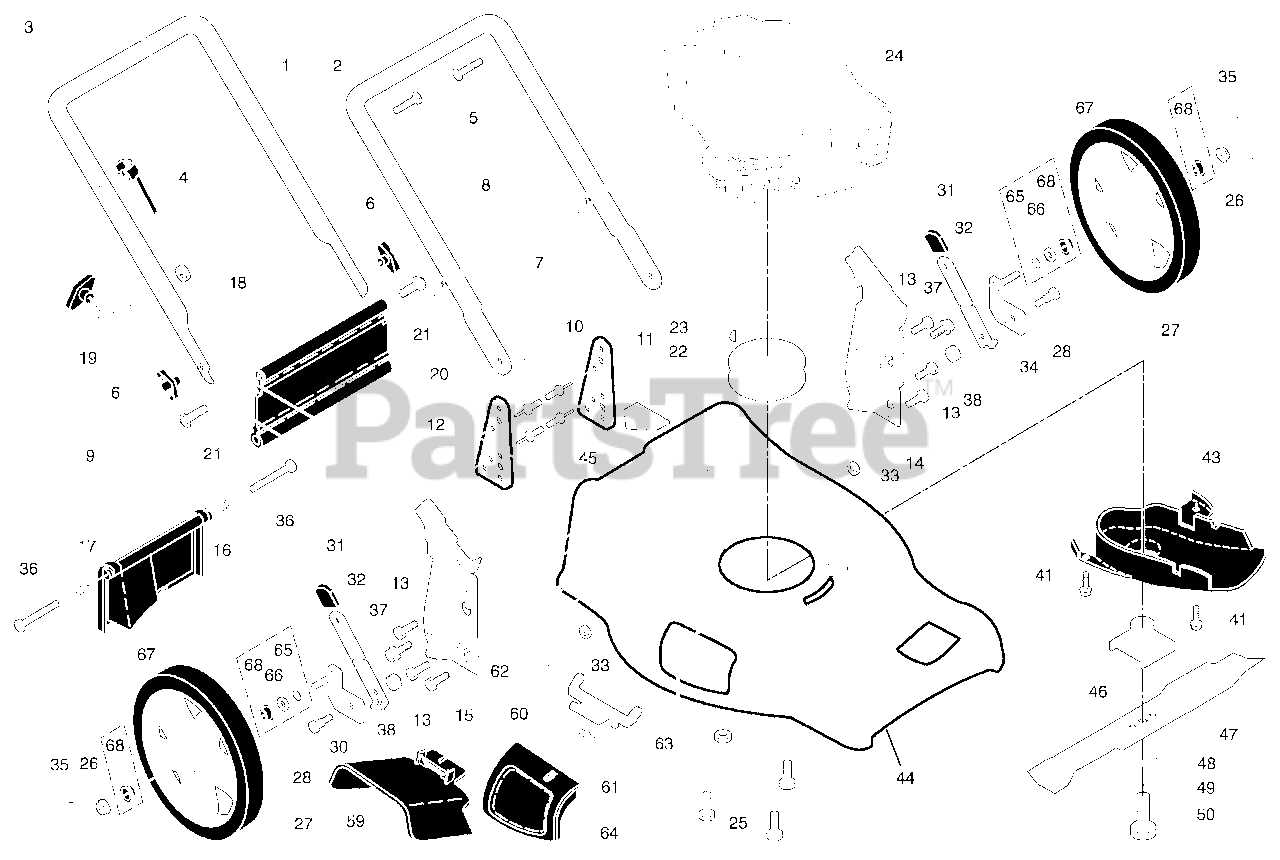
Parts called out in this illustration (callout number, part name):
1	Control Cable Assembly
2	Bearing, Wheel Adjuster
3	Pan Head Tapping Screw #10-24 x 2-3/4
4	Hex Washer Head Screw 1/4-20 x 2.12
5	V-Belt
6	Spring Retainer
7	Nut, Hex, Flanged 1/4-20
8	Hubcap
9	Locknut
11	Wheel & Tire Assembly
12	E-Ring
13	Pinion
14	Dust Cover
16	Washer 1/2
18	Selector Knob
28	Drive Cover
31	Nut, Hex, Flanged
32	Drive Pulley
35	Kit, Wheel Adjuster, LH
36	Gear Case Assembly
38	Locknut 1/4-20
40	Spring
41	Kit, Wheel Adjuster, RH
54	Grassbag Assembly
55	Driveshaft Cover
57	Frame, Grassbag
